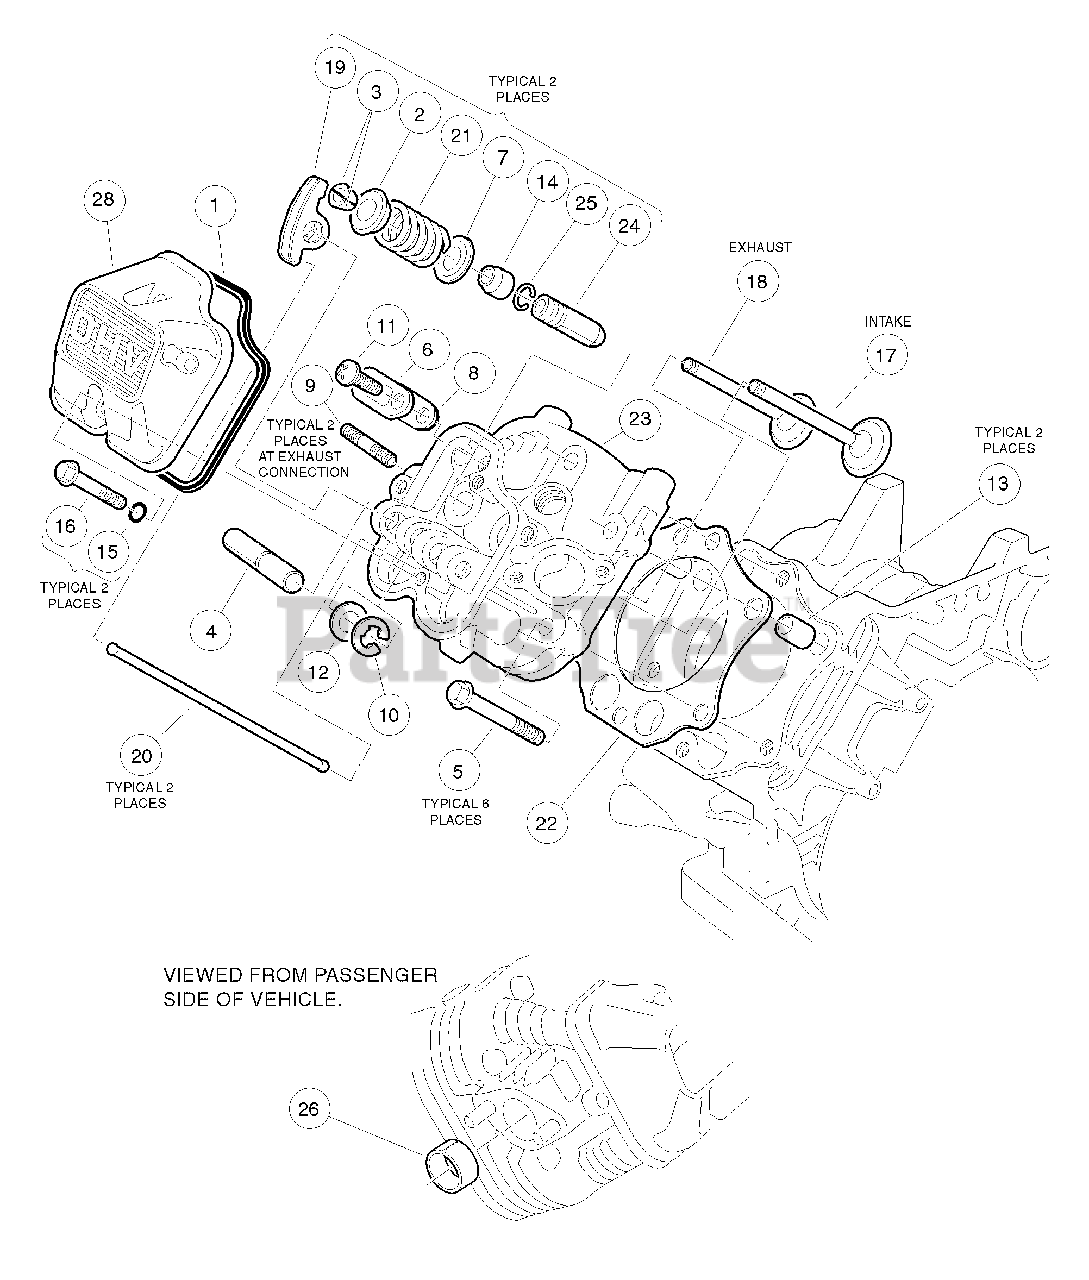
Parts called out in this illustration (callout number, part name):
1	Gasket, Rocker Case
2	Retainer, Valve Spring
4	Shaft, Rocker
5	Bolt, Flange Head, M8 x 1.25 x 45 mm
7	Seat, Spring
9	Stud, Two-Ended, M8-1.25
10	Circlip, Type-E
12	Washer, 12.1x19x1.8
14	Sea
16	Bolt, 6x35
17	Valve, Intake
18	Valve, Exhaust
19	Arm, Rocker
21	Spring, Engine Valve
22	Gasket, Head, FE400
23	Head, Cylinder, FE400
24	Guide, Valve, Intake
26	Sleeve, Exhaust
27	Kit, Gasket, FE400
28	Case, Rocker -w/o Logo Fe290
